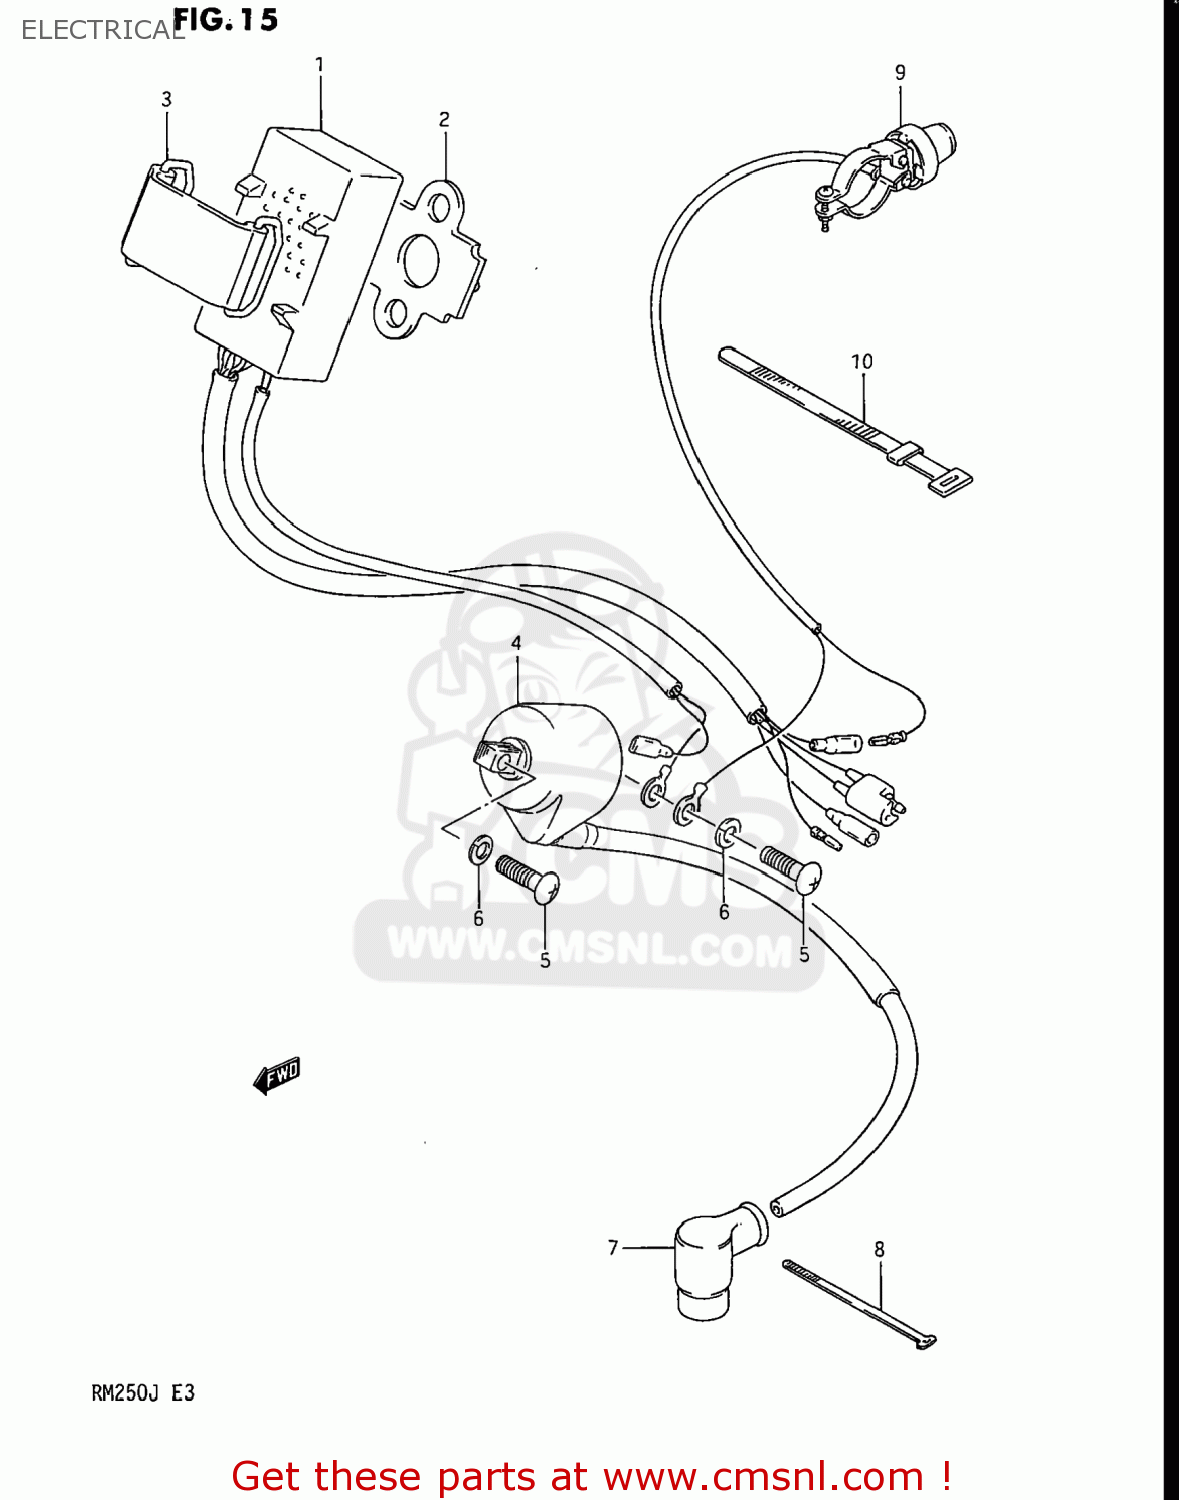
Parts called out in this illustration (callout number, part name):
1	UNIT,CDI
2	PROTECTOR,CDI UNIT
3	BAND
4	COIL ASSEMBLY,IGNITION
5	SCREW
6	WASHER,LOCK
7	CAP,SPARK PLUG
8	CLAMP
9	SWITCH ASSEMBLY
10	CLAMP(L:120)
